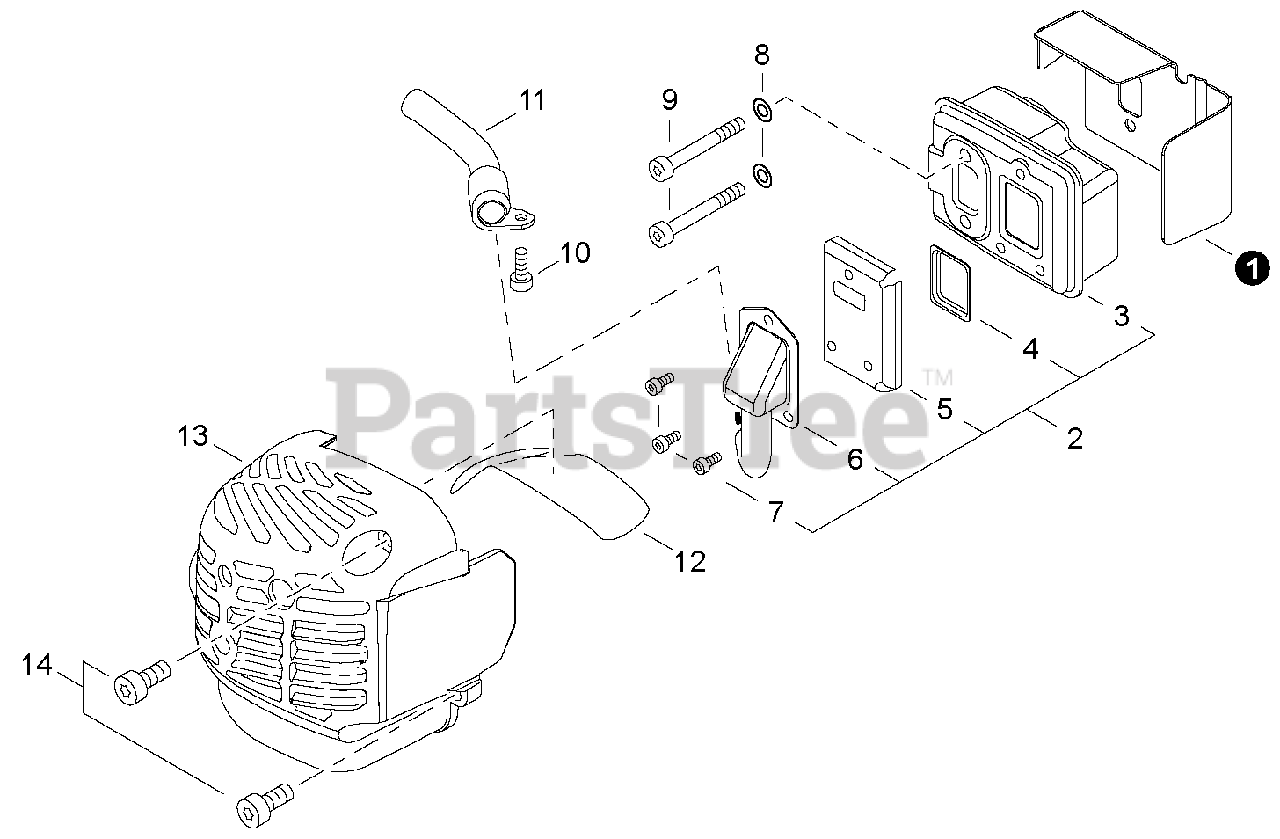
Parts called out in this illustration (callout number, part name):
1	HEAT SHIELD, EXHAUST
2	MUFFLER ASSY
3	MUFFLER
4	SCREEN, SPARK ARRESTER
5	GASKET, EXHAUST
6	GUIDE, EXHAUST
7	BOLT, TORX 4×8
8	WASHER 5.5×12×0.8
9	BOLT, TORX 5×55
10	BOLT, TORX 5×10
11	GUIDE, EXHAUST
12	PLATE, INSULATOR
13	COVER, MUFFLER
14	BOLT, TORX 5×16
